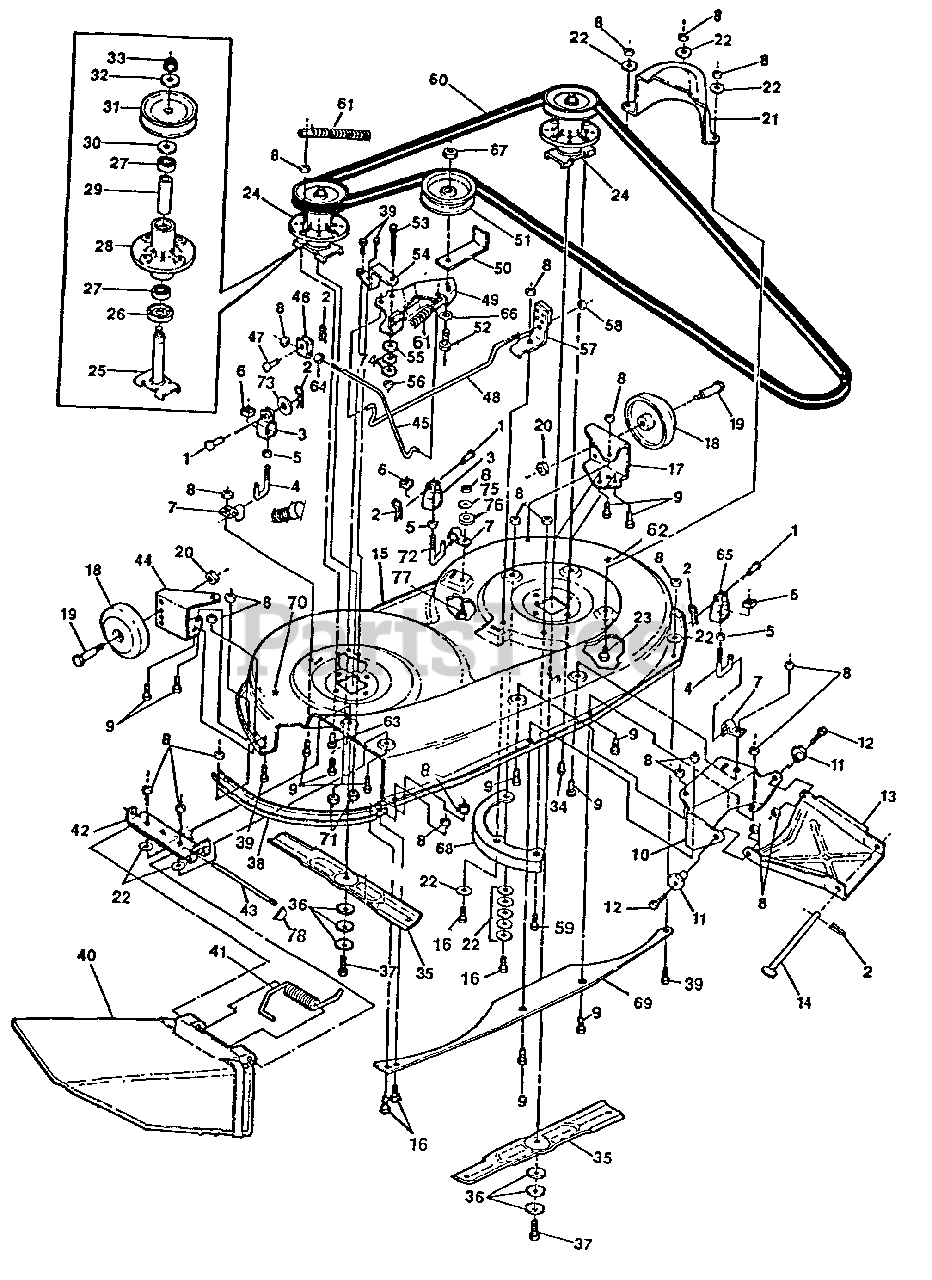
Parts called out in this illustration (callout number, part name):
1	Pin, Clevis
2	Hairpin, Cotter
4	Lift Rod
5	Nut, Hx Jam 1/2-13 Thd.
6	Nut, Sq. 1/2-13 Thd.
8	Nut, Hx, Lock 5/16-18 Thd
9	Screw, Hx Hd, 5/16-18 x 1 In.
10	Bracket, Front
11	Nut, Adjusting
12	Screw, Hx Hd. 5/16-18 x 1 In.
13	Channel, Draw Bar
14	Rod, Drawbar
15	Mower Deck
16	Screw, Hx, 5/16-18 x 3/4 In
17	Wheel Bracket, L H
19	Shoulder Bolt, 3/8-16 Thd.
20	Nut, Hex, Ctrlk, 3/8-16 Thd.
21	Belt Cover, Left Pulley
22	Flatwasher, 11/32 In.
23	Screw, Hx Hd, 5/16-18 x 5/8 In.
24	Quill Assembly
25	Saddle & Shaft Assembly
26	Dust Shield
27	Bearing
28	Quill Housing
29	Spacer Tube
33	Nut, Wd Fl, Lk 7/16-20 Thd.
34	Screw, Wshr Hd, 5/16-18 x 7/8"
36	Washer, Spring
37	Screw, Hx Hd, 3/8-24 x 1 In
38	Toe Guard
39	Screw, Hx Hd, 5/16-18 x 3/4 In
40	Chute Deflector
42	Bracket, Chute Mount
43	Rod, Chute
44	Wheel Bracket, R. H.
45	Clutch Rod
46	Clevis, Clutch
47	Pin, Clevis
48	Rod, Brake
49	Idler Assembly
49	Idler Arm
49	Brake Pad
50	Belt Retainer
51	Idler Pulley
52	Carriage Bolt, 3/8-16 x 2 In
53	Shoulder Bolt, 3/8-16 x 3/4 In
54	Idler Brace
55	Washer, Flat
56	Nut, Hx, Wd Fl, 3/8-16 Thd
57	Brake Spring Assembly
58	Nut, Hx, Ctrlk, 1/4-20 Thd.
59	Screw, Hx, 5/16-18 x 1-1/4 In
60	Belt, 82 In Long
62	Decal, No Step
63	Screw, Tap, 5/16-18 x 1-3/8 In
64	Nut, Hx, 5/16-18 Thd.
66	Washer, Split, Lock 3/8 In
67	Nut, Hx, 3/8-16 Thd
68	Baffle, Deck
69	Baffle, Deck Front
70	Decal, Danger
71	Nut, 5/16-18 Thd
72	Lift Rod
73	Washer, Flat
74	Washer, Flat
75	Washer, Flat
77	Screw, 5/16-18 x 1 In.
78	Push Nut
